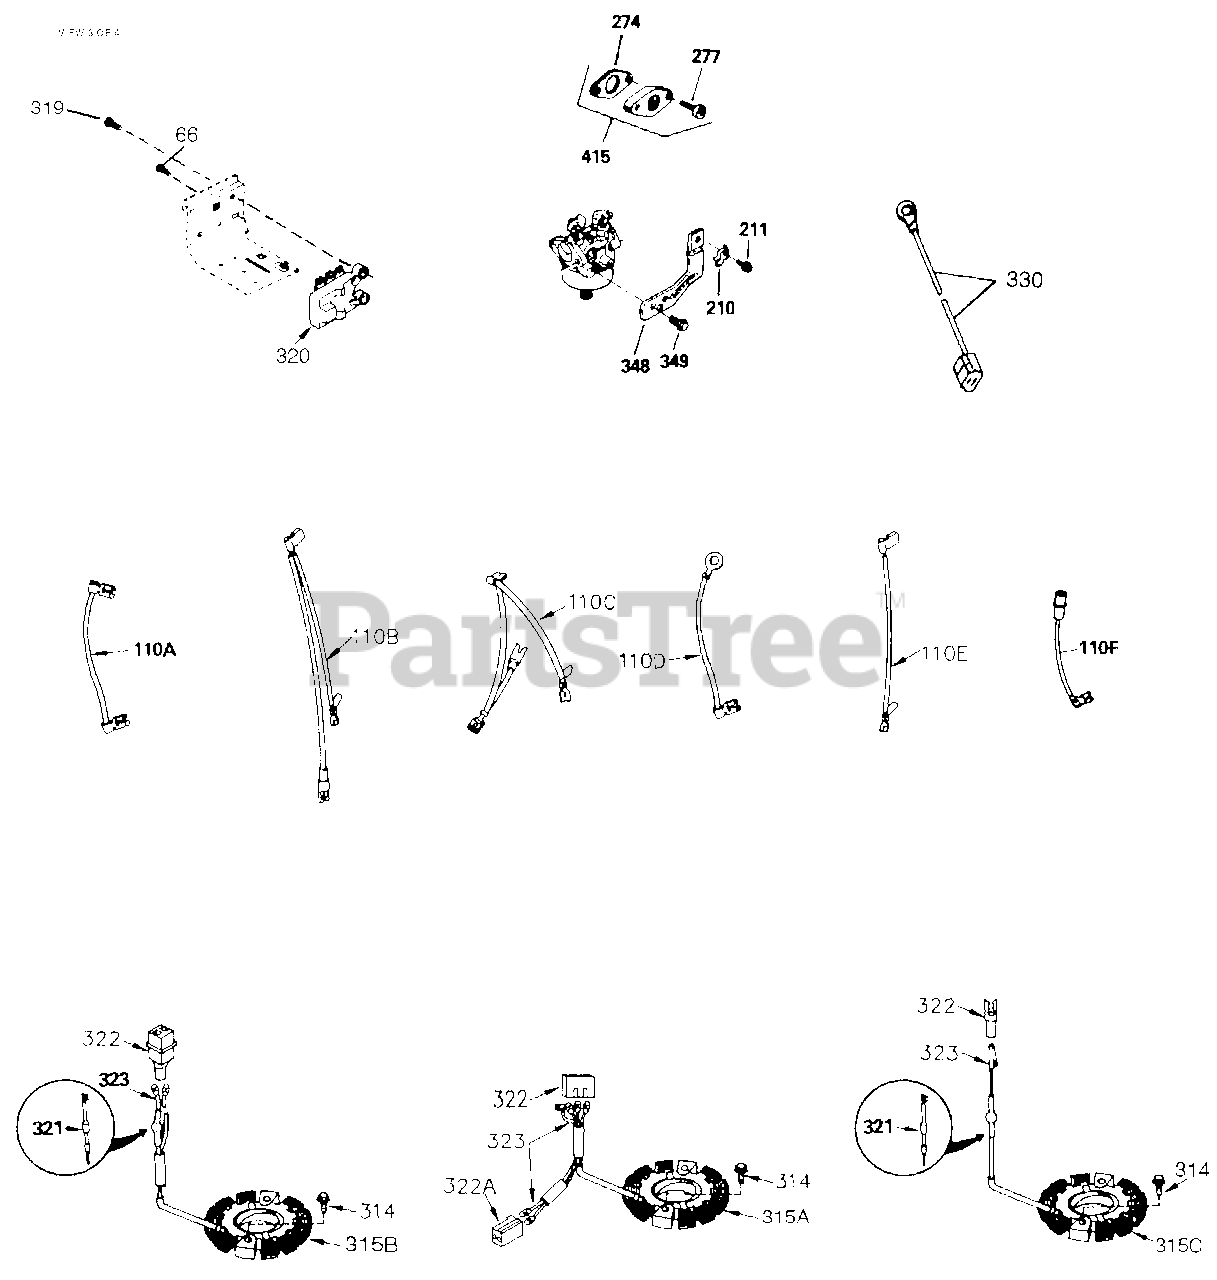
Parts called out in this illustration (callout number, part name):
72A	Oil Drain Plug
159	Rocker Arm Cover Gasket
274	Exhaust Manifold Gasket
306	Oil Fill Tube Gasket
361A	Screw, 1/4-20 x 1-13/32"
